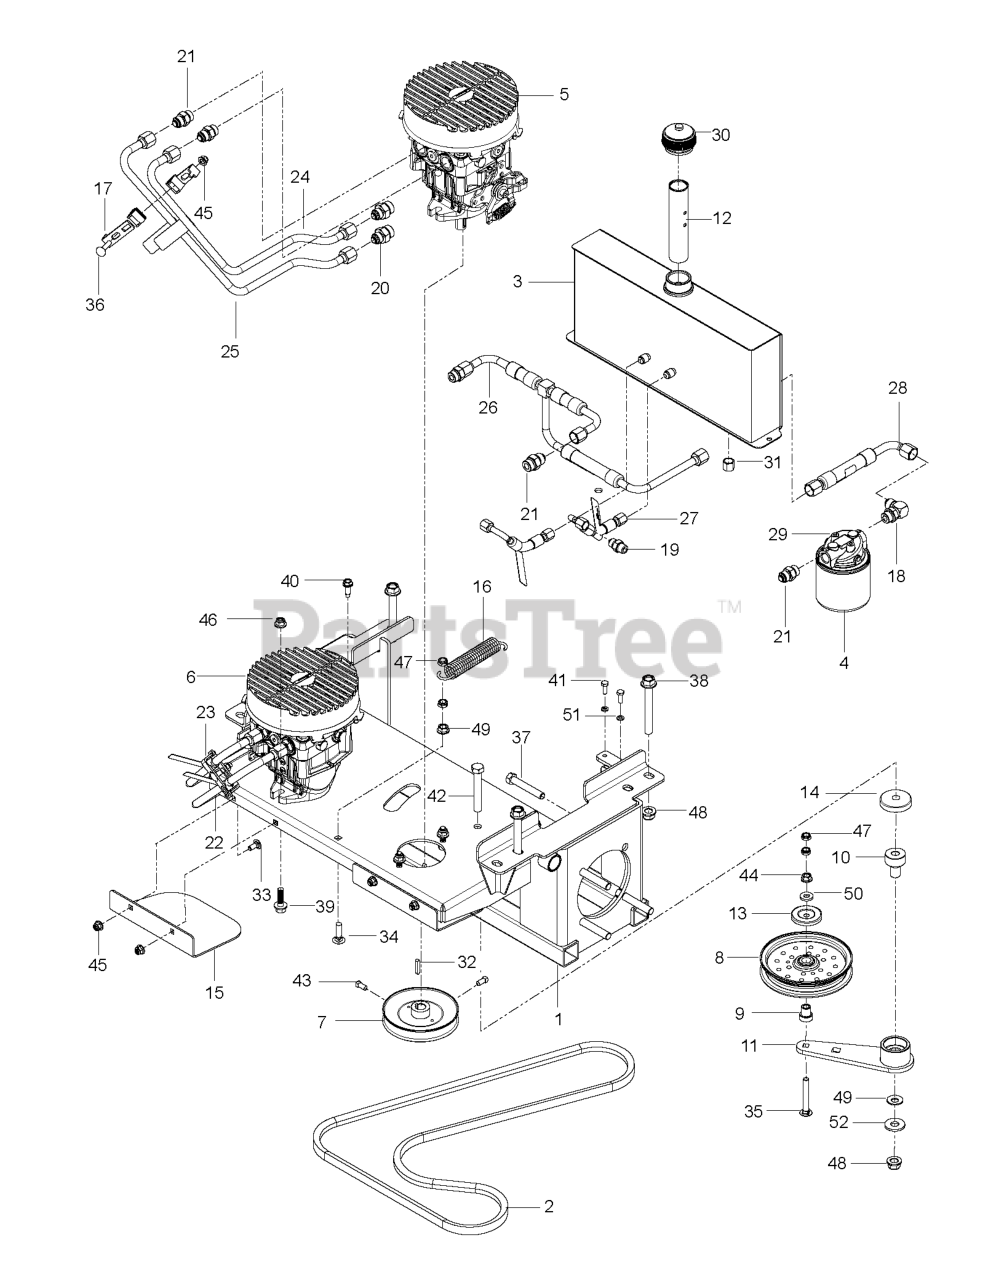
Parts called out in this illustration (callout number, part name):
1	FRAME, NYDR SUB, BLK
2	BELT, "B", 75.5"
3	ASSEMBLY, RESERVOIR, OIL
4	FILTER 25 MICRON
5	HG_PUMP, 16CC
6	HG_PUMP, 16CC
7	PULLEY, PUMP 17MM
8	IDLER, FLAT, 5.5"
9	PIVOT, IDLER
10	PIVOT, BEARING
11	ARM, IDLER, STEEL, W/BGS
12	TUBE, ANTI-SPLASH
13	DUST SHIELD
14	SHIELD, DUST
15	SHIELD, PULLEY, BLK
16	SPRING, PUMP
17	ASM, VIB, HYDRO HOSE
18	ELBOW, 90 DEGREE
19	STRAIGHT FITG
20	CONNECTOR, STRAIGHT
21	FITTING, STRAIGHT F6400-8-8-0
22	LINE, RT A
23	LINE, RT B
24	LINE, LT A
25	LINE, LT B
26	LINE, CHARGE
27	LINE, CASE
28	LINE, SUCTION
29	FILTER HEAD
30	CAP, HYDRAULIC
31	NUT 9/16-18 JIC CAP
32	KEY 5 MM SQ X 25 MM
33	BOLT 5/16-18 X3/4 ZN/YEL GR 5
34	BOLT.3/8-14X1.25
36	BOLT
37	HCS 1/2-13 X 2-3/4 GD 5 ZD
38	HHFS 1/2-13 X 4.0 GD8 ZD
39	HHFS 3/8-16 X 1.25 GD 5
40	SCREW
41	HCS 1/4C X 5/8
42	HCS 1/2-13 X 3-1/4 GD 5 ZD
43	SCREW 5/16C X 5/8 SQ HEAD
44	NUT 3/8C WHIZ
45	5/16-18 NYLOC FLANGE NUT
46	NUT 3/8-16 HEX FLG NYLOC ZD
47	NUT HEX 3/8-16 NYLON, THIN
48	NUT, 1/2-13 HEX FLG NYLOC ZD
49	CONTACT BELLSPR 1/2
50	WASHER, 3/8 THICK
51	LOCKWASHER 1/4"
52	WASHER.9/16 X 1 3/8 X 12 GA.
